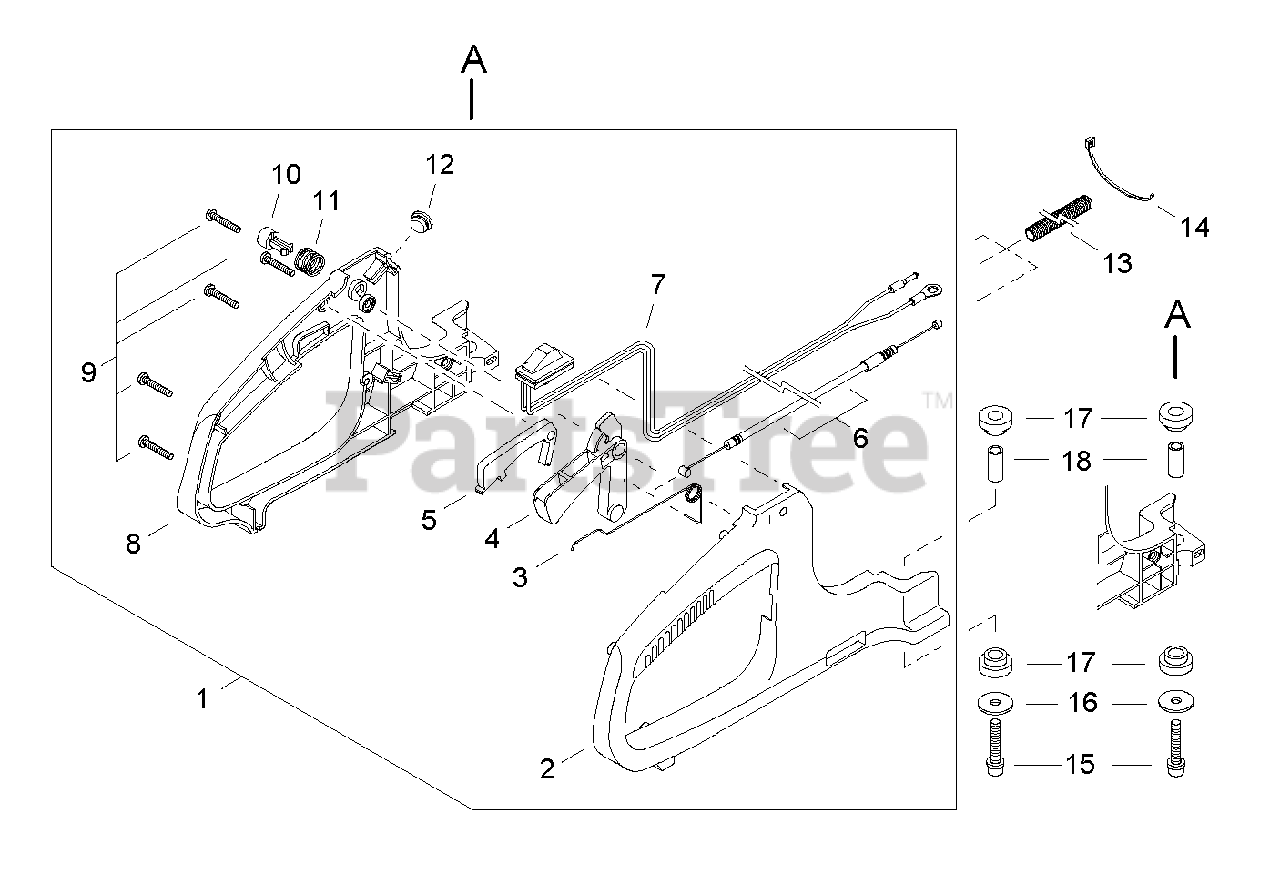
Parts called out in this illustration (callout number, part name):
1	HANDLE ASSY, REAR
2	CONTROL HANDLE - RIGHT
3	SPRING, THROTTLE RETURN
4	TRIGGER, THROTTLE
5	LEVER, THROTTLE LOCKOUT
6	CABLE ASSY, THROTTLE
7	SWITCH, ON-OFF
8	CONTROL HANDLE - LEFT
9	SCREW, TAPPING Ø4×18
10	BUTTON, THROTTLE LOCK
11	SPRING, COMPRESSION
12	PLUG, RUBBER
13	TUBE, FLEXIBLE
14	STRAP, TIE
15	BOLT M6×35
16	WASHER Ø23ר6.5×2 MM
17	CUSHION
18	COLLAR 6
